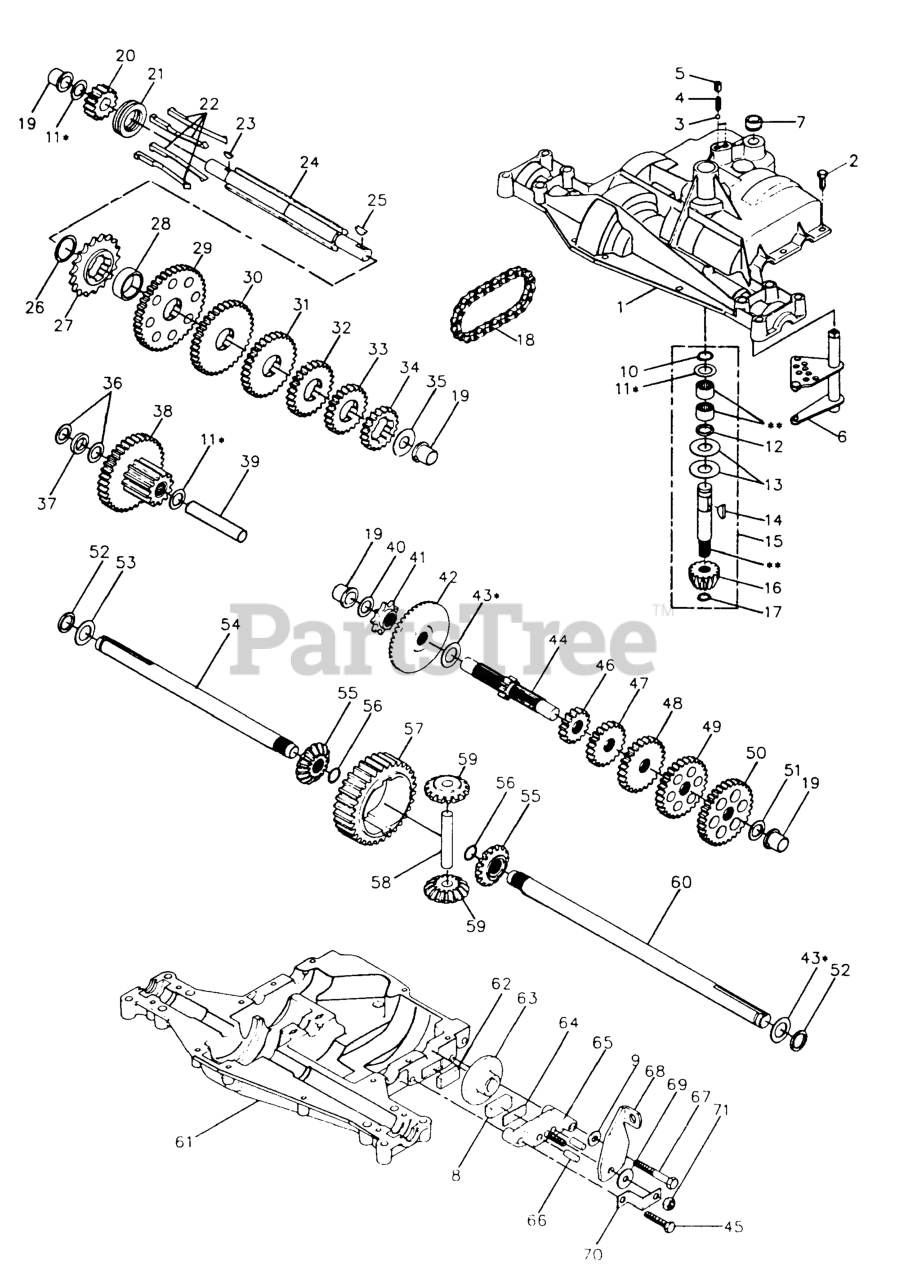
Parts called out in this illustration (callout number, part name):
1	Housing, Upper
2	Screw, Tapping 1/4 - 20 x .734 L
3	Ball, Detent
4	Spring, Detent
5	Screw, Set
6	Assembly, Shifter
8	Puck, Friction
9	Washer, Plain, .325 x .750 x .059
10	Ring, Retaining
11	Washer, Plain, .632 x 1.00 x .010
11	Washer, Plain, .632 x 1.00 x .020
11	Washer, Plain, .632 x 1.00 x .026
11	Washer, Plain, .632 x 1.00 x .031
11	Washer, Plain, .632 x 1.00 x .036
11	Washer, Plain, .632 x 1.00 x .041
11	Washer, Plain, .632 x 1.00 x .046
11	Washer, Plain, .632 x 1.00 x .050
11	Washer, Plain, .632 x 1.00 x .060
11	Washer, Plain, .632 x 1.00 x .082
13	Washer, Plain, .632 x 1.38 x .046
14	Key, Woodruff # 9
15	Assembly, Kit, Input Shaft
16	Pinion, Bevel, 14 T
17	Ring, Retaining
18	Chain, 24 Pitches
19	Bearing, Flange
20	Gear, Spur, 14T
21	Collar, Clutch
22	Key, Clutch
23	Key, Woodruff # 3
24	Shaft, Intermediate
25	Key, Woodruff # 61
26	Ring, Retaining
27	Sprocket, 18 T
29	Gear, Spur, 40 T
30	Gear, Spur, 35 T
31	Gear, Spur, 30 T
32	Gear, Spur, 25 T
33	Gear, Spur, 22 T
34	Gear, Spur, 19 T
35	Washer, Plain, .640 x 1.37 x .061
36	Washer, Plain, .632 x 1.00 x .026
37	Spacer, .630 x 1.00 x .169
38	Assy., Gear, Comb., 12 T & 35 T
39	Shaft, Idler
40	Washer, Plain, .631 x 1.00 x .015
41	Sprocket, 9 T
42	Gear, Bevel, 42 T
43	Washer, Plain, .758 x 1.12 x .010
43	Washer, Plain, .758 x 1.12 x .015
43	Washer, Plain, .758 x 1.12 x .020
43	Washer, Plain, .758 x 1.12 x .025
43	Washer, Plain, .758 x 1.25 x .020
43	Washer, Plain, .758 x 1.25 x .025
43	Washer, Plain, .758 x 1.25 x .031
43	Washer, Plain, .758 x 1.25 x .035
43	Washer, Plain, .758 x 1.25 x .040
43	Washer, Plain, .758 x 1.25 x .045
43	Washer, Plain, .758 x 1.25 x .050
44	Shaft, Drive
45	Screw, Tapping, 5/16 x 18 x 1.44 Lg.
46	Gear, Spur, 15 T
47	Gear, Spur, 20 T
48	Gear, Spur, 25 T
49	Gear, Spur, 28 T
50	Gear, Spur, 31 T
51	Washer, Plain, .632 x 1.00 x .060
52	Seal, Felt
53	Washer, Plain, .758 x 1.25 x .062
54	Axle, L.H.
55	Gear, Miter, 15 T
56	Ring, Retaining
57	Gear, Spur, 32 T
58	Shaft, Cross
59	Gear, Miter, 15 T
60	Axle, R.H.
61	Housing Lower
62	Puck, Friction
63	Disc, Brake
65	Jaw, Brake
66	Pig, Jowel
67	Screw, Tapping, 5/16 - 18 x 2.25
68	Lever, Actuating
69	Washer, Plain, .321 x 1.00 x .055
70	Bracket, Anti-Rotation
71	Nut, Lock 5/16 - 24
